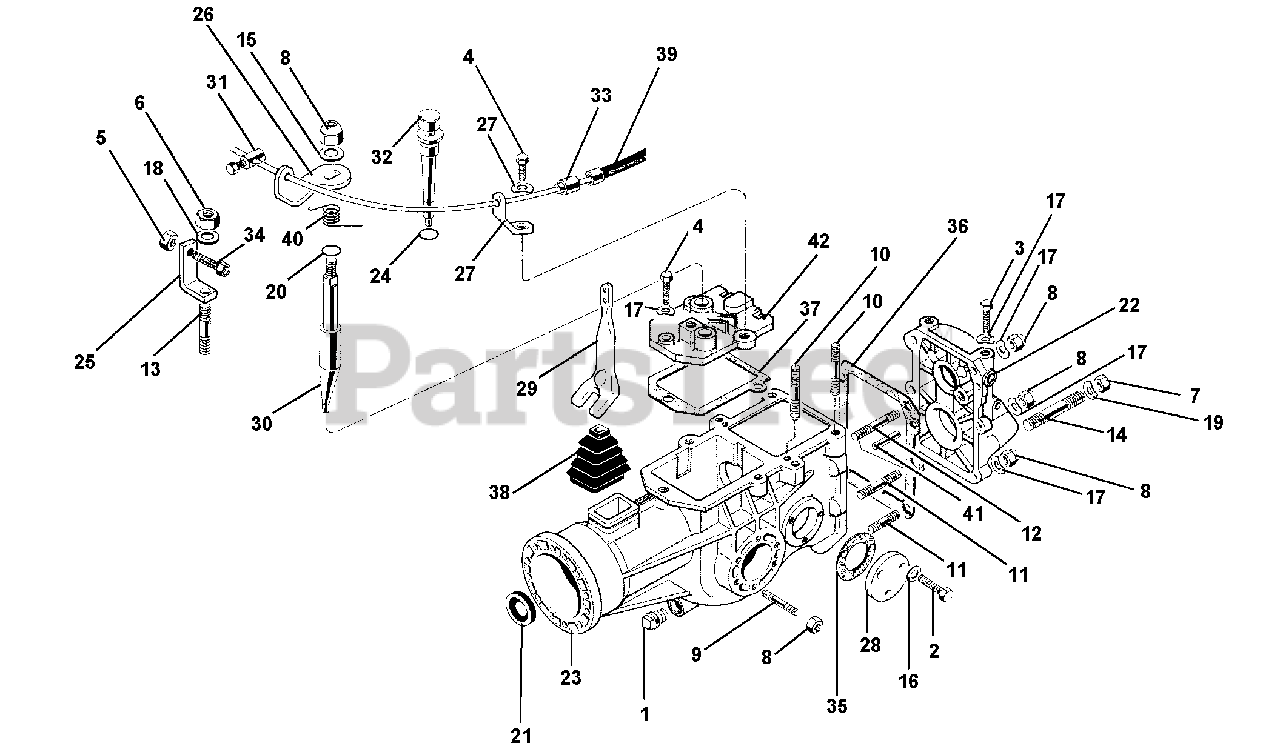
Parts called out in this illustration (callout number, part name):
1	PLUG 1/4 GAS
2	SCREW TE M6 X 10 UNI 5739-5S
3	SCREW M8 X 20
4	SCREW TE M8 X 30
7	NUT M12 X 1.25 UNI 5587 6S
8	NUT, SELF LOCKING M8
9	STUD M8 X 46 X 20 X 12
10	STUD M8 X 38 X 14 X 20
11	STUD M8 X 46 X 16 X 16
12	STUD M8 X 58 X 16 X 16
13	STUD M10 X 37 X 19 X 15 8G
14	STUD 56XM12X1.25X26XM12X22 8G
15	WASHER, FLAT 8.4
16	WASHER, LOCK 6.4
17	WASHER, LOCK 8.4
18	WASHER, LOCK 10.5
19	WASHER, LOCK 13
20	O-RING 2056 14.00 X 1.78
23	GEARBOX 745/606-605
24	RUBBER RING
25	BRACKET CLUTCH CONTRAST
26	LEVER RELEASE
27	CONTRAST DIFFERENTIAL SHEATH
29	CLUTCH LEVER
31	CLAMP, CABLE
32	CAP, WITH MEASURING ROD
33	END, SHEATH
34	SCREW, ADJUSTING M8
36	GASKET, COVER
37	GASKET, COVER
39	CABLE & SHEATH, CLUTCH
41	PARALLEL PIN D 6 X 20
42	COVER DIFFERENTIAL
